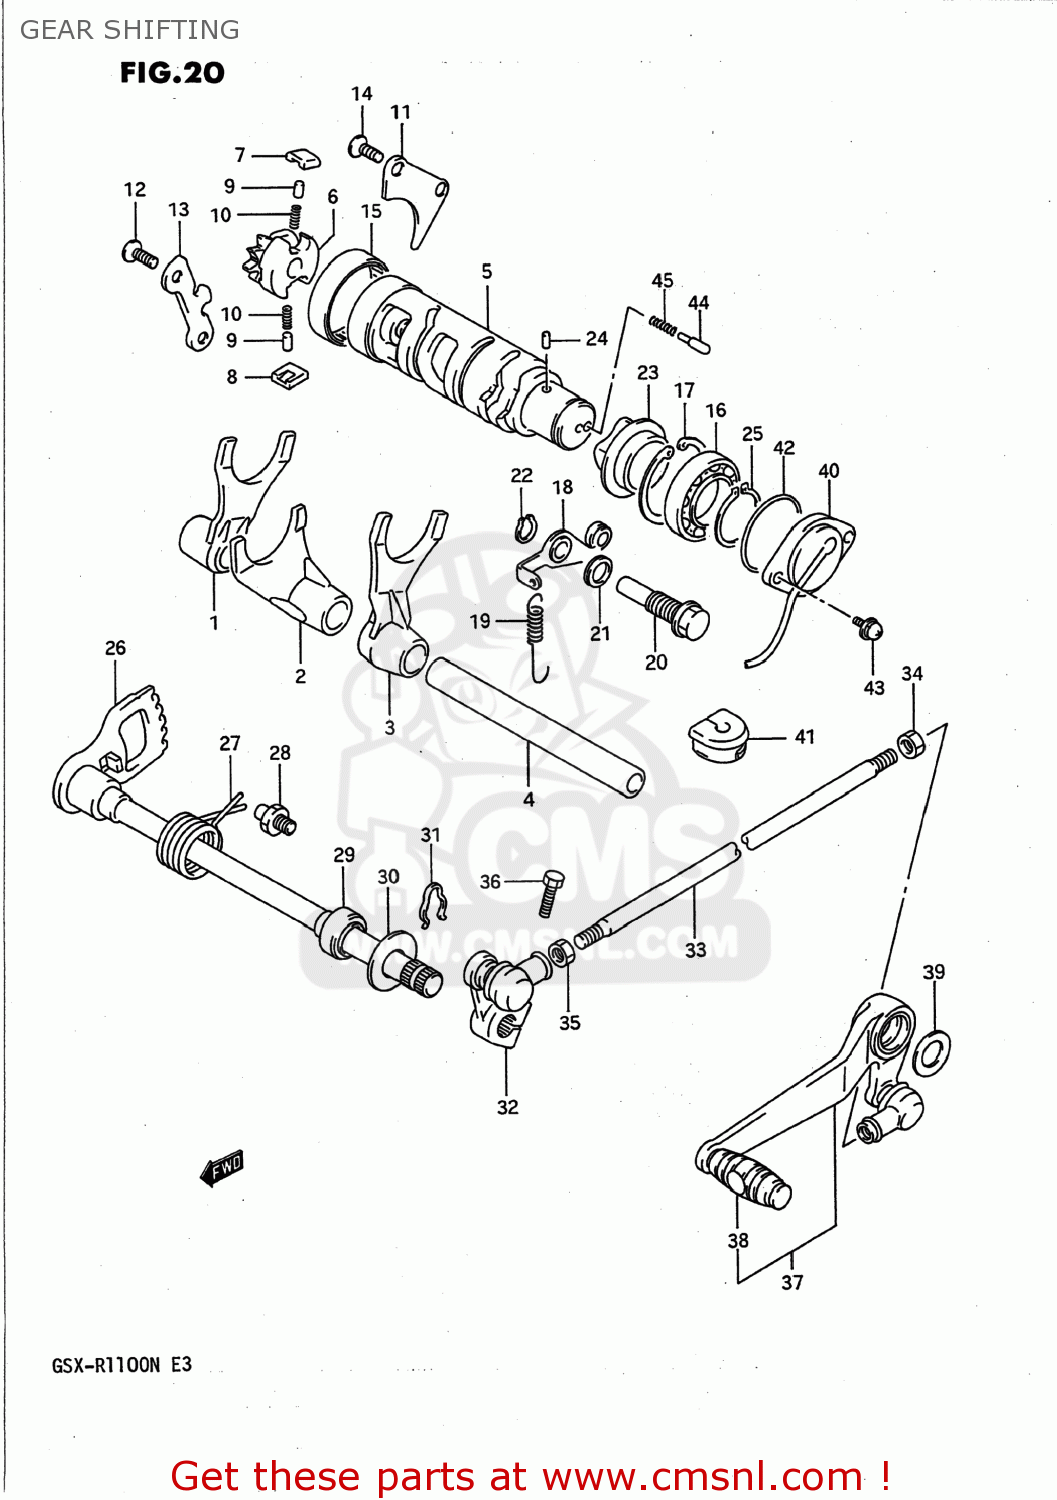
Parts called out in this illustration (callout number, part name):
1	FORK,GEAR SHIFT NO.1
2	FORK,GEAR SHIFT NO.2
3	FORK,GEAR SHIFT NO.3
4	SHAFT,GEAR SHIFT FORK(L:128)
5	CAM,GEAR SHIFT
6	GEAR,GEARSHIFT CAM DRIVE
7	PAWL,GEAR SHIFT NO.1
8	PAWL,GEAR SHIFT NO.2
9	PIN(5X8)
10	SPRING
11	LIFTER,GEAR SHIFT PAWL
12	SCREW
13	GUIDE,GEAR SHIFT CAM
14	SCREW
15	BEARING(43X49X12)
16	BALL BEARING
17	CIRCLIP
18	STOPPER,GEAR SHIFT CAM
19	SPRING
20	SHAFT,GEAR SHIFT CAM STOPPER
21	GASKET(10X14X3.6) (NAS)
22	CIRCLIP
23	PLATE,STOPPER
24	PIN 4X6
25	CIRCLIP
26	SHAFT,GEAR SHIFT
27	SPRING
28	STOPPER,GEAR SHIFT CAM
29	OIL SEAL
30	WASHER (12.5X27X1.6)
31	SPRING,RETAINER
32	ARM,GEAR SHIFT LINK
33	ROD,GEAR SHIFT LINK
34	NUT
35	NUT 6MM
36	BOLT
37	LEVER ASSEMBLY,GEAR SHIFTING
38	RUBBER,GEAR SHIFT PEDAL
39	WASHER(18X24X1)
40	BASE ASSY,GEAR SHIFT TERMINAL
41	GROMMET,LEADWIRE
42	O RING(D:2.4,ID:36.5)
43	SCREW
44	PIN(5X15.5)
45	SPRING
